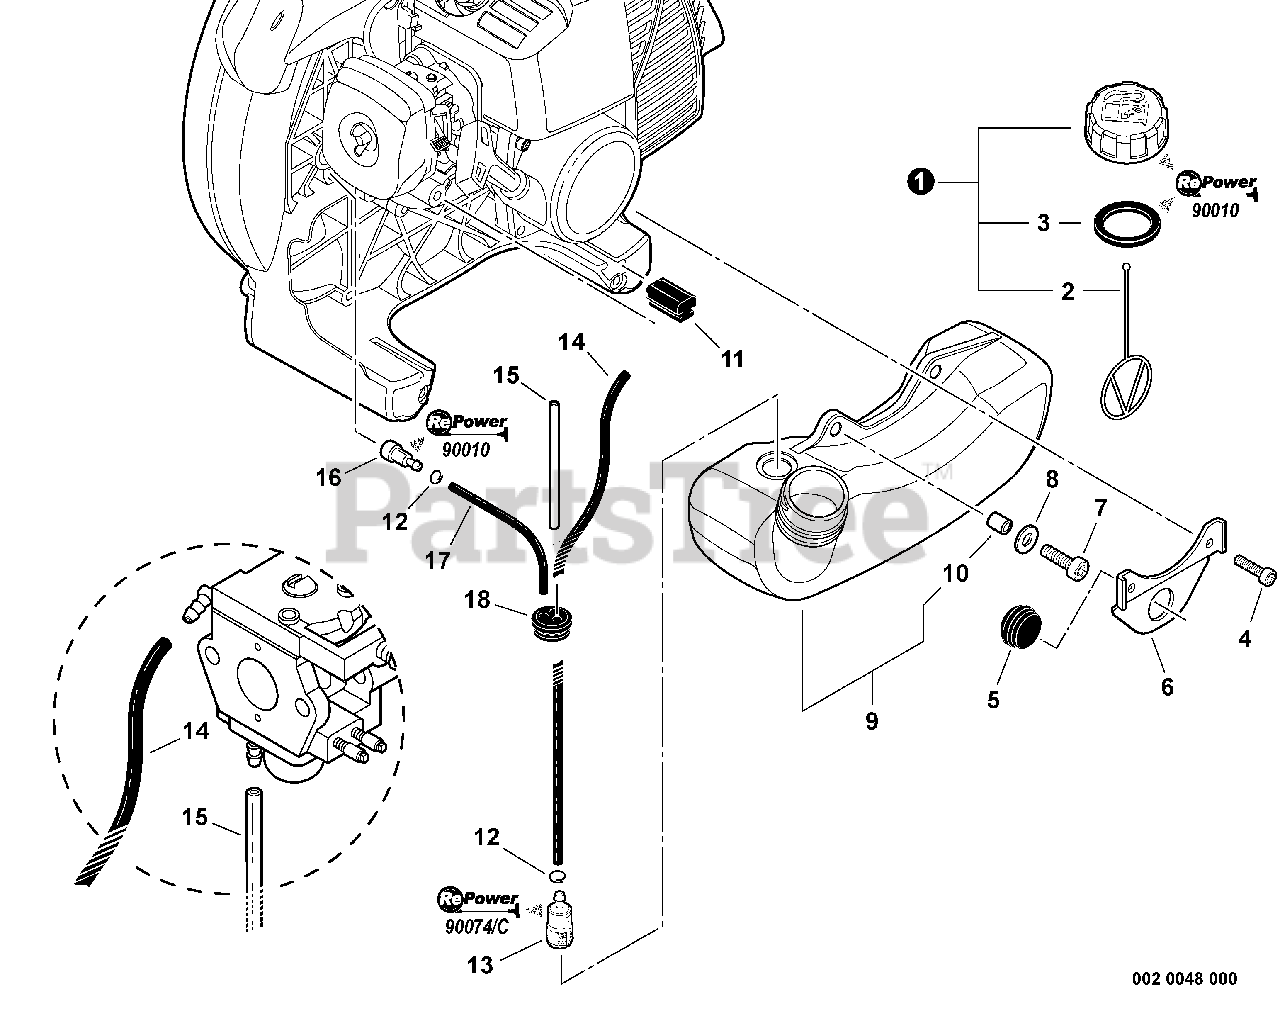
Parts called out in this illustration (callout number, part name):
1	CAP ASSY, FUEL
2	CONNECTOR, CAP L= 100 MM
3	GASKET, FUEL CAP
4	BOLT, TORX 4×16
5	CUSHION
6	BRACKET, FUEL TANK
7	BOLT, TORX 5×16
8	WASHER 5.5×12×0.8
9	TANK ASSY, FUEL
10	SPACER 6.2×7.8×6
12	CLIP 6 MM
13	FILTER, FUEL
14	PIPE, FUEL 3×5×230 BLACK
15	PIPE, FUEL 3×6×85 CLEAR
16	VENT ASSY
17	PIPE, FUEL 3×5×80 BLACK
18	GROMMET, FUEL
19	CAP/VENT KIT - REPOWER
20	TUNE-UP KIT - REPOWER
